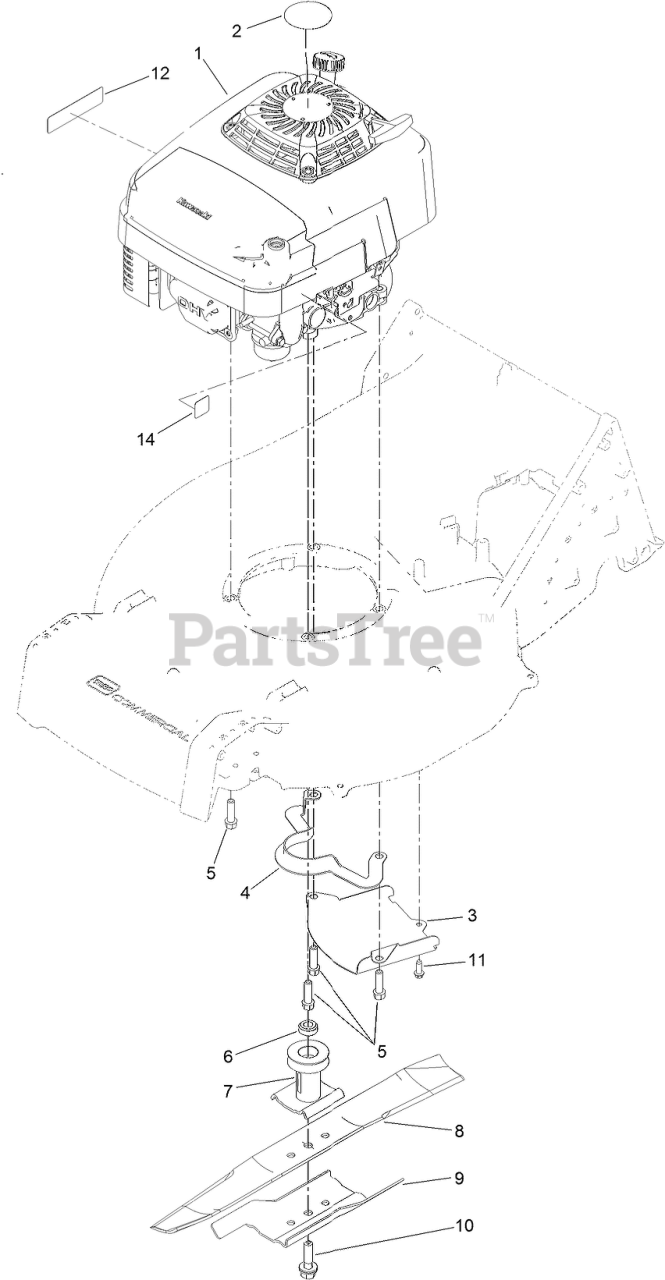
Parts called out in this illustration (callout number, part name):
1	ENGINE-KAWASAKI, FJ180V
3	SHIELD-GRASS
4	GUIDE-BELT
5	SCREW-TAPTITE
6	SPACER-DRIVER, BLADE
7	DRIVER-BLADE
8	BLADE-RECYCLING
9	ACCELERATOR-BLADE
10	BOLT-BLADE
11	SCREW-HWHTF
12	DECAL-ARRESTER, SPARK
14	DECAL-PRIMER
